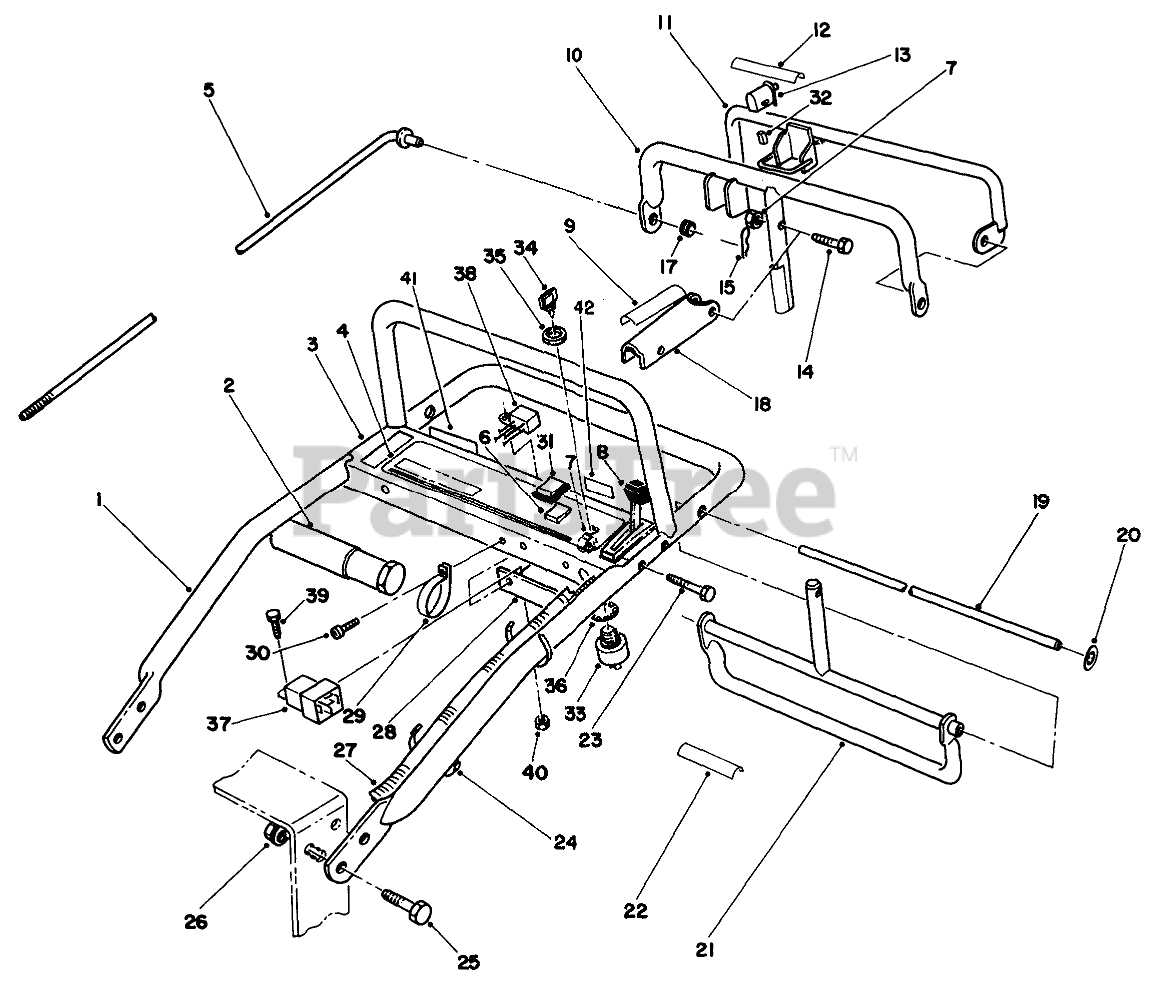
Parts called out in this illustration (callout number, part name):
1	Handle-Upper
2	TUBE-MANUAL
3	Panel-Control
4	DECAL-CONTROL PANEL
5	ROD-CONTROL
6	SWITCH
7	NUT-LOCK, NI
8	CONTROL-THROTTLE
9	DECAL-LEVER, PARKING
10	Bar
11	Bail
12	DECAL
13	SWITCH-BAIL
14	SCREW-SHH
15	PIN-COTTER
17	GROMMET-RUBBER
18	Lever-Parking Brake
19	PIVOT ROD
20	NUT-PUSH-ON, CIRCULAR
21	Control Pivot
22	DECAL
23	SCREW-SHH
24	TIE-CABLE
25	SCREW-HHF
26	NUT-HF
27	WIRE HARNESS
28	Panel-Bottom
29	CLAMP-R
30	SCREW-HWHTF
31	BOOT-SWITCH
32	CONNECTOR-BODY
33	Switch-On/Off (Incl. Ref. #34-36)
34	KEY-IGNITION
35	NUT-HH
36	WASHER-TOOTH, INTERNAL
37	RELAY
38	Module
39	SCREW-HH
40	NUT-LOCK, NI
41	DECAL/INSTRUMENT PANEL
42	DECAL-INSTRUCTION
